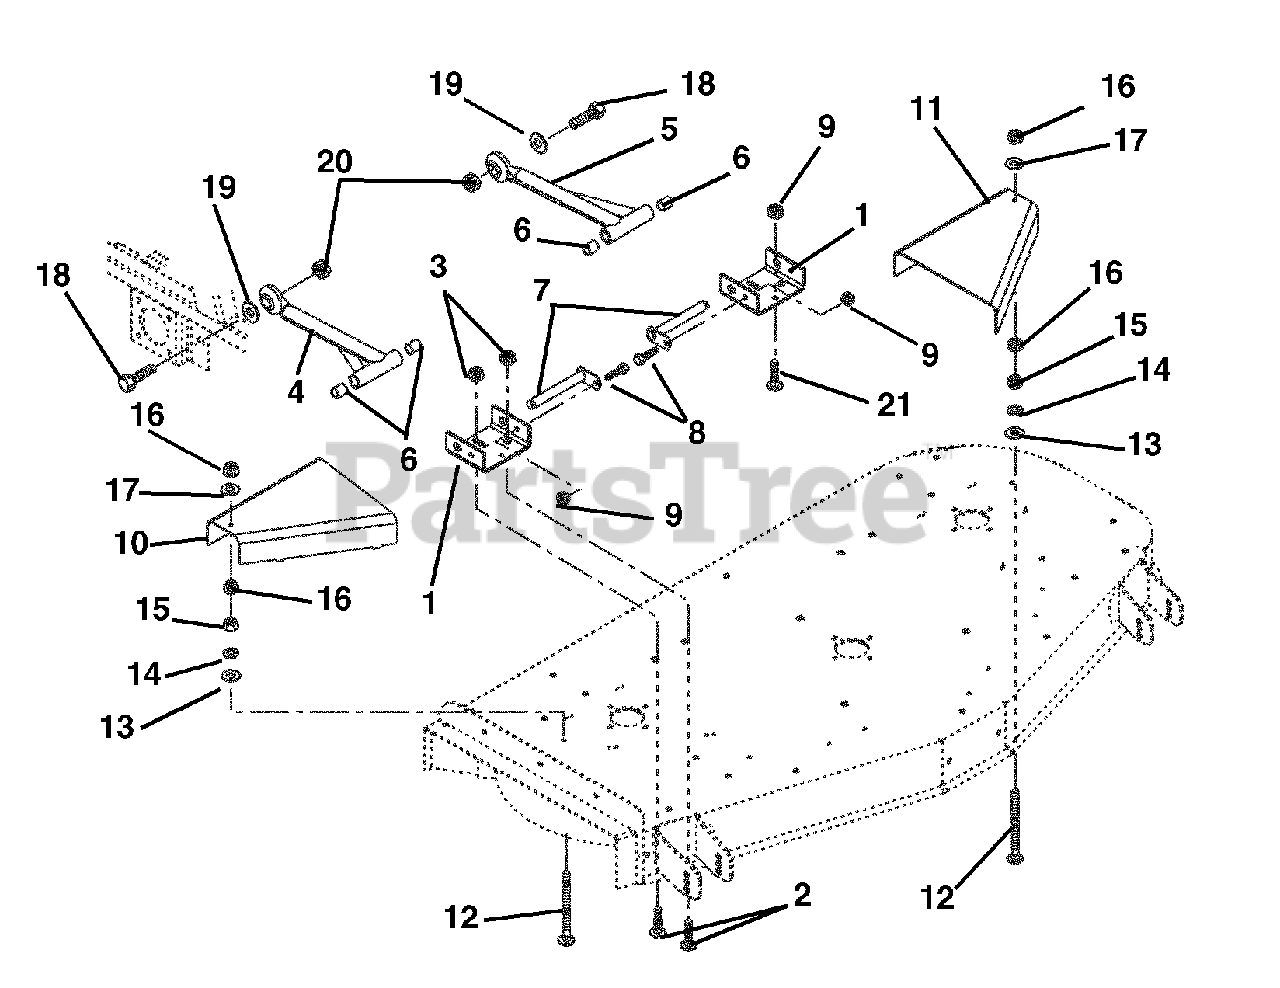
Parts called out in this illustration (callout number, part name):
1	Bracket, Mower Mounting (Rear)
2	Bolt-Round Head Square Neck .50-13 x 1.00 Grade 2
3	Nut-Locking-Center .50-13
4	Assembly, Mower Mounting Arm
5	Weldment-Mower Mounting Arm
6	Bearing .75 x .875 x 1.00
7	Weldment, Mower Mounting Pin
8	Bolt-Hex .38-16 x .75 Grade 5
9	Nut-Locking-Center .38-16
10	Guard, Pulley Right Hand (036, 038, 309)
10	Guard, Pulley Right Hand (037, 039)
11	Guard, Pulley Left Hand (036, 038, 309)
11	Guard, Pulley Left Hand (037, 039)
12	Bolt-Round Head Square Neck .31-18 x 3.50
13	Washer-Flat-Steel .344 x .688 x .065
14	Washer-Locking .31 x .078
15	Nut-Hex .31-18
16	Nut-Locking-Center .31-18
17	Washer-Flat-Steel .438 x 1.00 x.083
18	Bolt-Hex .875-9 x 2.75 Grade 5
19	Washer-Flat-Steel .875 x 1.50 x .120
20	Nut-Locking-Center .875-9
21	Bolt-Round Head Square Neck .38-16 x 1.00 Grade 5
